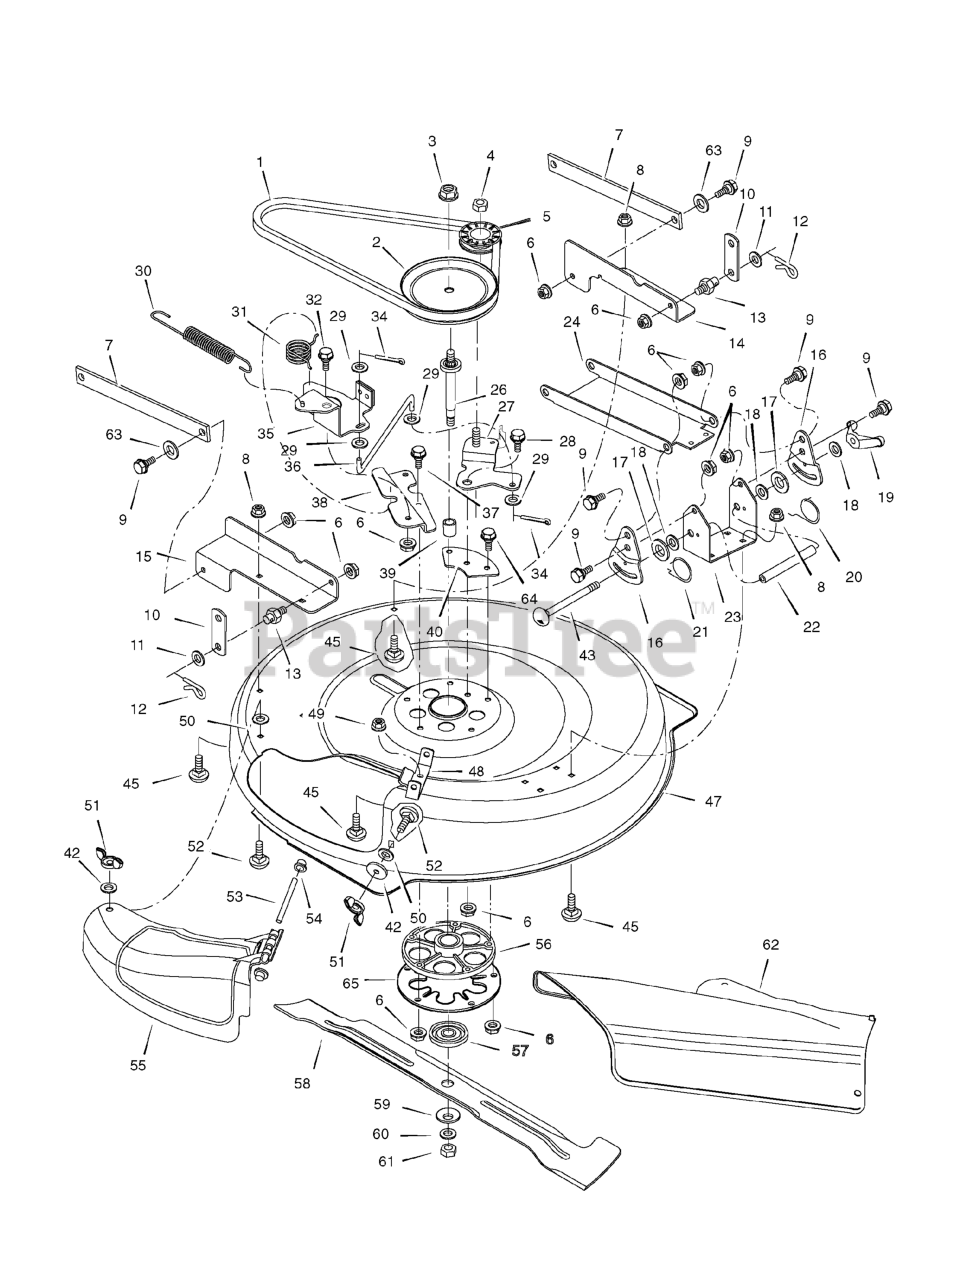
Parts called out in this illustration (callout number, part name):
1	Belt, Blade Drive
2	Pulley, Input
3	Locknut
4	Nut, Flange
5	Pulley, Idler
6	Nut, Flange
8	Nut, Flange
9	Bolt, Shoulder
12	Pin, Hair
13	Pin, Threaded Shoulder
14	Bracket, Left Rear
15	Bracket, Right Rear
16	Plate, Adjustment
17	Pad, Friction
19	Wingnut
20	Spring, Left Torsion
21	Spring, Right Torsion
22	Tube, Spacer
23	Bracket, Deck
24	Hanger, Front
26	Shaft, Splined
27	Arm Assembly , Idler
28	Bolt, Shoulder
29	Washer
30	Spring, Extension
31	Spring, Torsion
32	Bolt, Shoulder
34	Pin, Cotter
35	Arm Assembly, Brake
36	Link, Idler Arm
37	Bolt
38	Bracket, Brake Mounting
39	Spacer, Jackshaft
40	Plate, Idler Mounting
43	Bolt, Carriage
45	Bolt, Carriage
47	Housing, Blade
48	Hinge, Mulching Cover
49	Nut, Flange
50	Nut, Speed
51	Wingnut
52	Bolt, Carriage
53	Rod, Chute Deflector
54	Cap, Push
55	Cover, Mulch
56	Mandrel Housing
57	Adapter, Blade
59	Washer, Cup
61	Nut, Blade Mount
62	Deflector, Chute
65	Plate, Jackshaft Support
